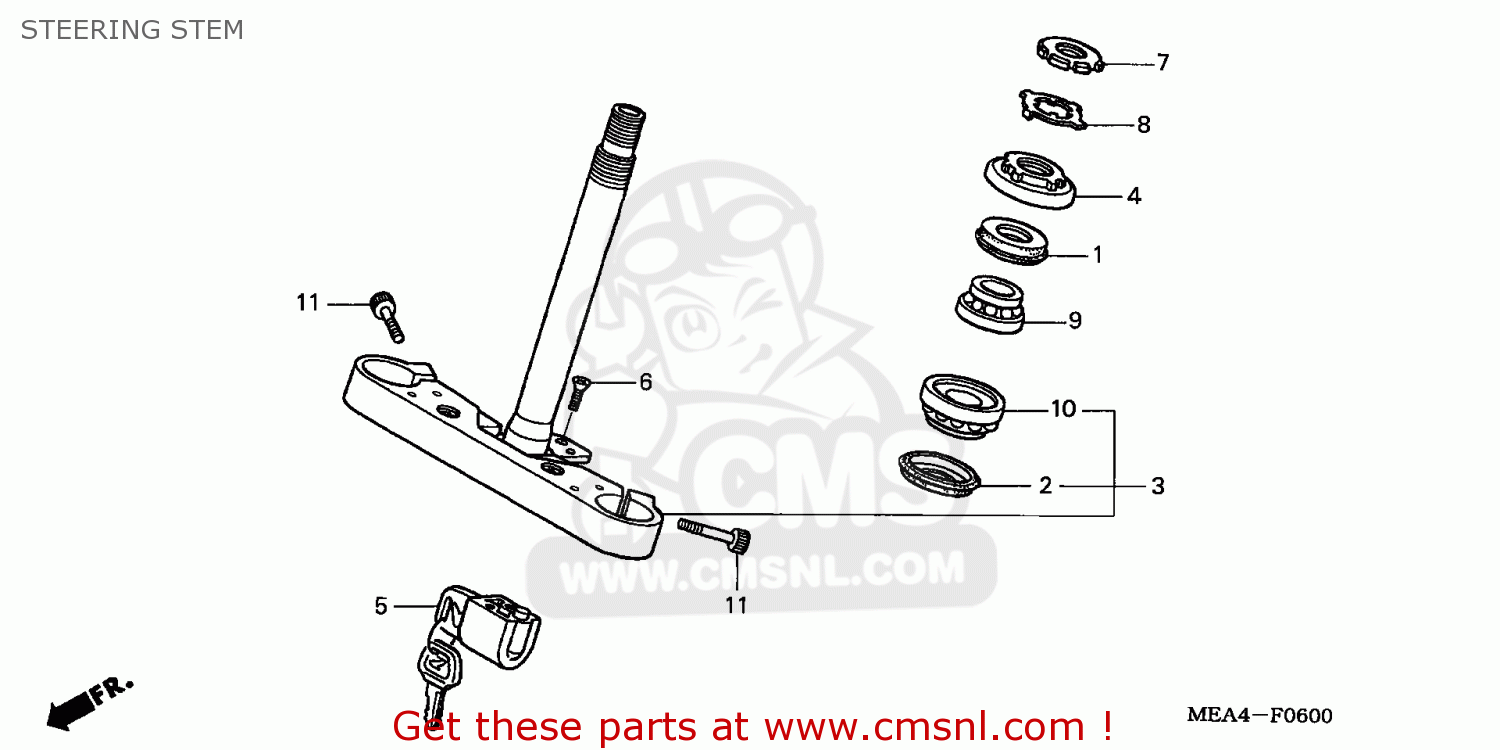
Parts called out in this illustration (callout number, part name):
1	DUST SEAL,STRG UP
2	SEAL,HEAD DUST
3	STEM SUB ASSY,STR
4	THREAD,STRG.HEAD
7	THREAD B,TOP
8	WASHER
9	B/BRG RAD N/COM
10	B/BRG RAD N/COM
11	SOCKET BOLT,10X28
